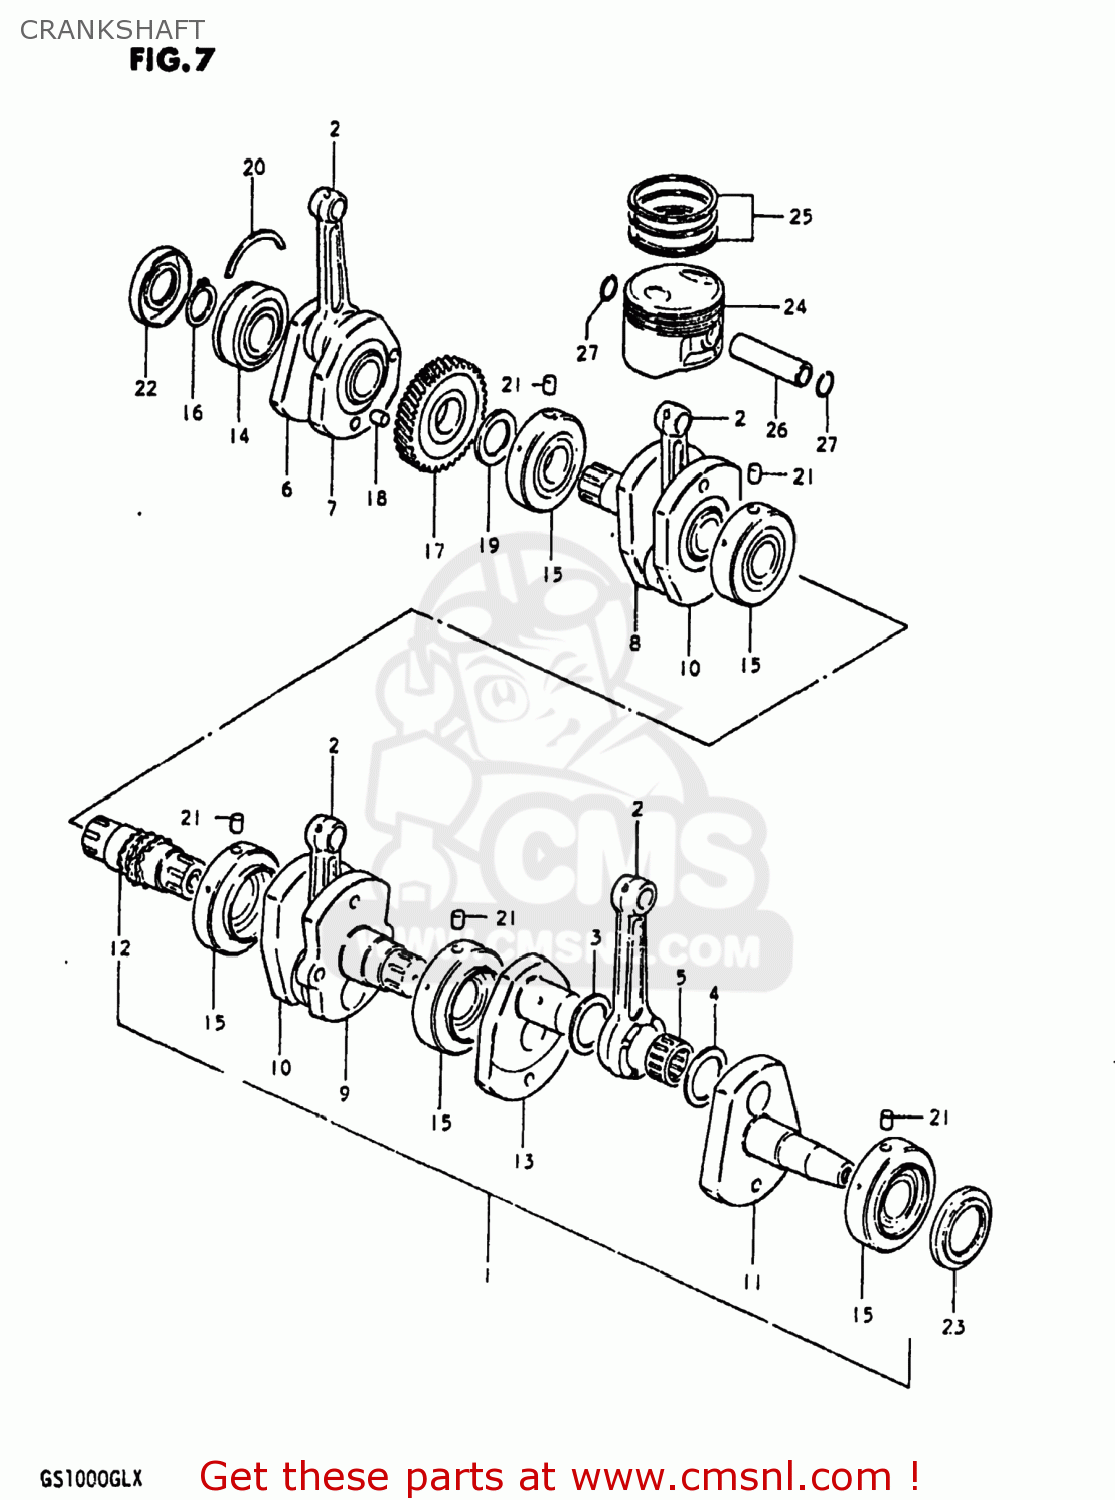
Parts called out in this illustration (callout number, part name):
1	CRANKSHAFT ASSEMBLY
2	ROD,CONNECTING
3	WASHER (29X48X2)
4	WASHER (29X48X1)
5	BEARING(29X39X20)
6	CRANKSHAFT
7	CRANKSHAFT
8	CRANKSHAFT
9	CRANKSHAFT
10	WEB,CRANK,MIDDLE
11	CRANKSHAFT,LEFT
12	SHAFT,TIMING CHAIN DRIVE
13	WEB,CRANK
14	BEARING(30X72X19)
15	BEARING
16	CIRCLIP,30MM
17	GEAR,PRIMARY DRIVE
18	PIN
19	WASHER
20	C RING
21	PIN
22	SEAL,OIL(30X72X11)
23	SEAL,OIL(47.3X60X6.5)
24	PISTON
25	RING SET,PISTON
26	PIN,PISTON (18MM)
27	CIRCLIP
